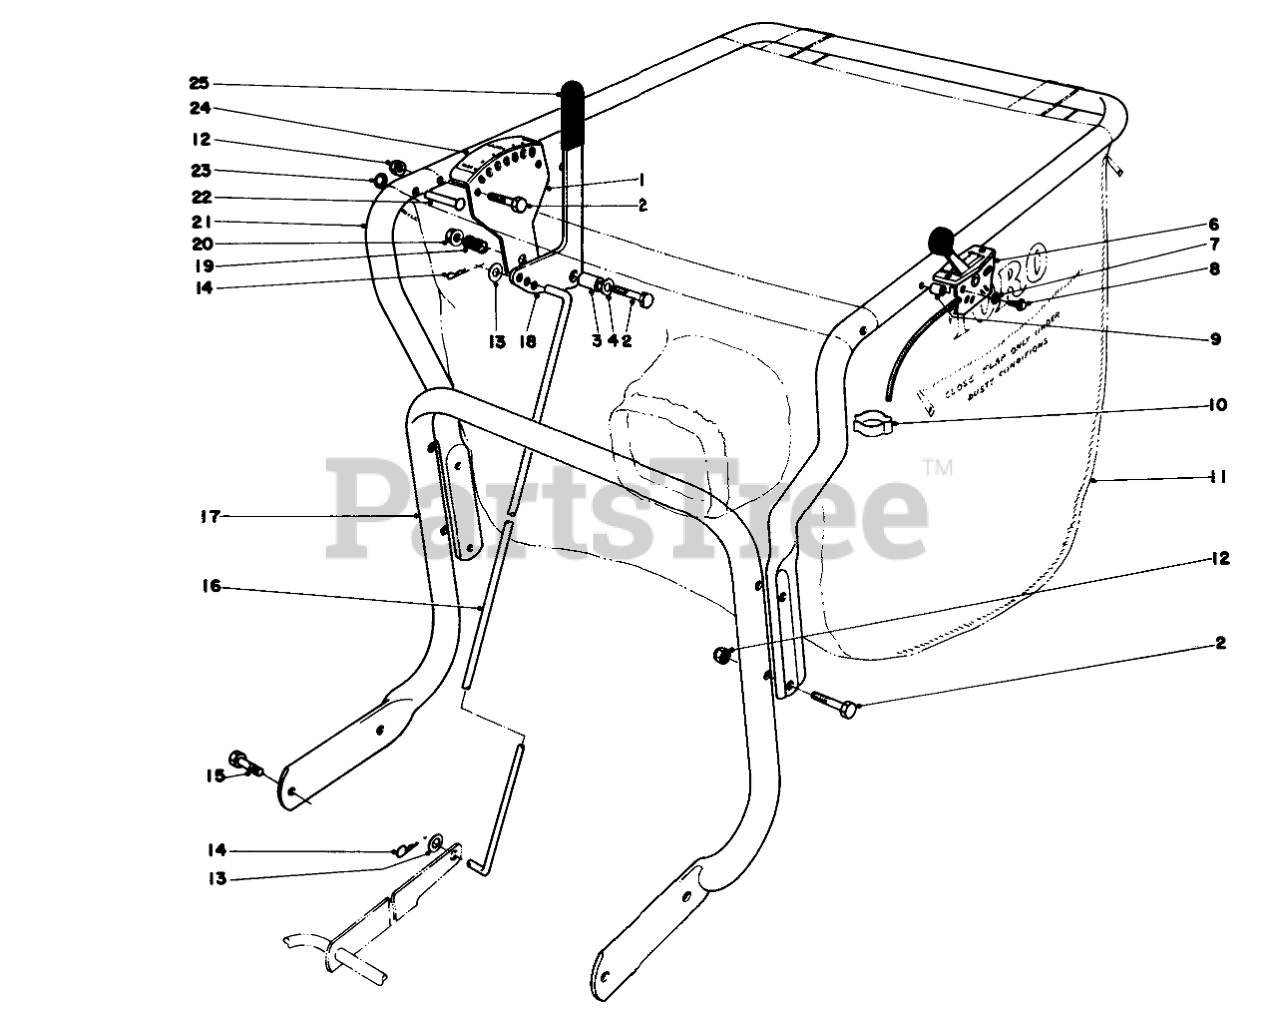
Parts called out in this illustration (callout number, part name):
1	Adjustment Bracket
2	SCREW-HH
3	SPACER
4	WASHER-FLAT
6	THROTTLE CONTROL
7	WASHER-LOCK, EXT
8	10-24 X 1 PAN HD SCR
9	SPACER
10	BODEN CLIP
11	EDGER DISK BEARING
12	NUT-LOCK, CONE
13	WASHER-FLAT
14	PIN-COTTER
15	SCREW-HH
16	HEIGHT ADJ. ROD
17	HANDLE
18	Handle-Adjustment
19	SPRING-COMPRESSION
20	NUT-HF
21	HANDLE-UPPER, VACUUM
22	RIVET
23	NUT-PUSH IN
24	HT ADJ DECAL
25	GRIP-HANDLE
